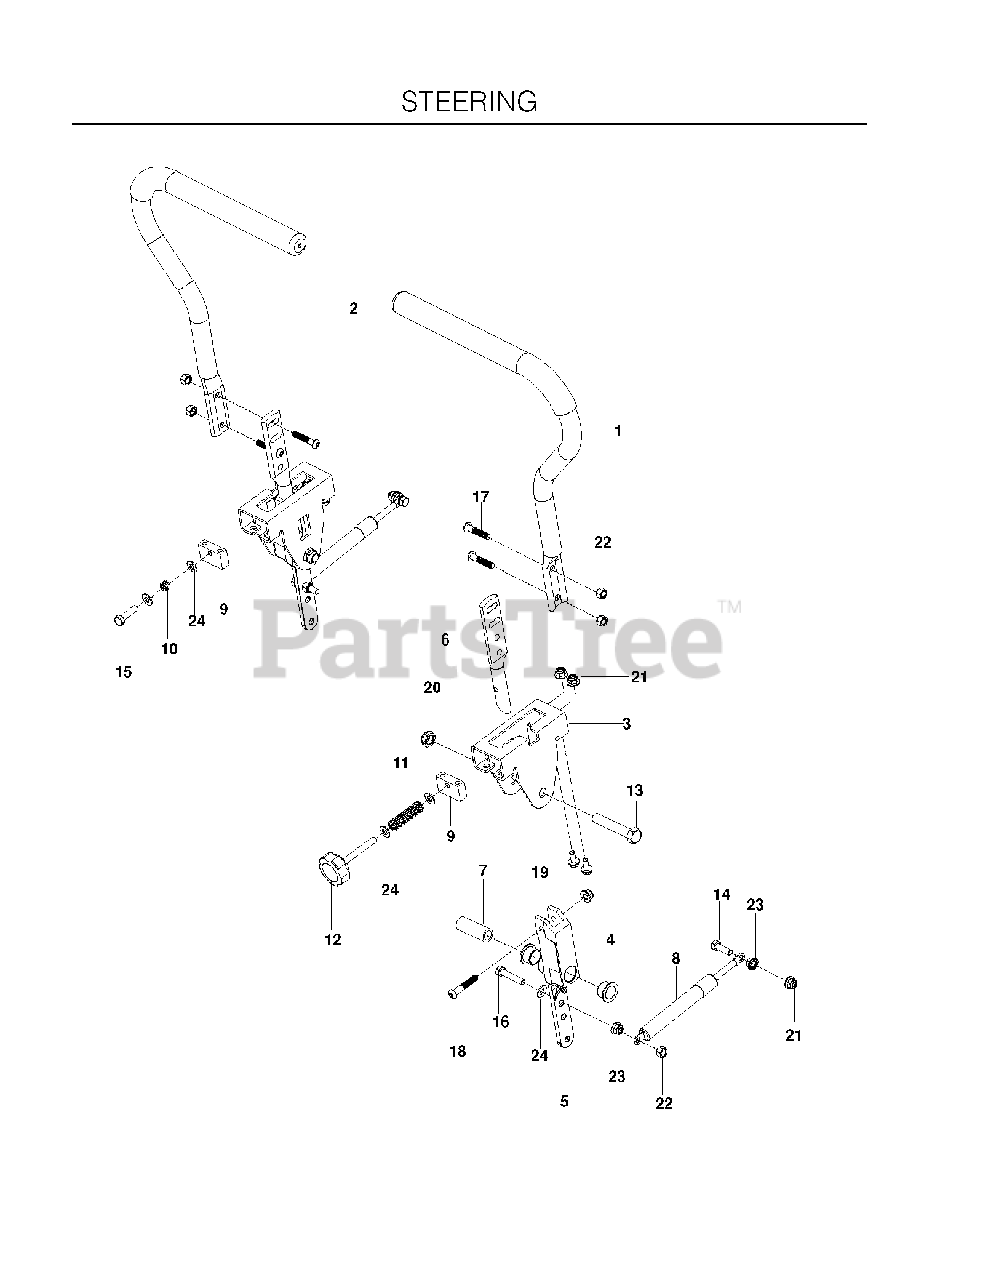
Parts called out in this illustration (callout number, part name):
1	LEVER.STEERING.ASM.(W/GRIP)
2	GRIP, DRIVE LEVER
3	BRACKET, CONTROL
4	BEARING, FLANGE
5	LEVER CONTROL PIVOT
6	LEVER.HANDLE MOUNT
7	SPACER, PIVOT CONTROL
9	BLOCK.TRACKING
11	SPRING COMPRESSION 2.0
13	HCS 1/2C X 2 3/4
14	HCS 5/16C X 1
15	CAPSCREW 5/16 X 1/1/2 HEX HEAD
16	BOLT 1/4C X 1 3/4
17	SCREW BUTTONHEAD 5/16-18X1-1/2
18	SCREW 5/16-18 X 1 3/4 BTN-HD
19	HHFS 5/16-18 X 3/4
20	NUT 1/2-13 HEX JM NYL
21	5/16-18 NYLOC FLANGE NUT
22	NUT 5/16 NYLOC
23	NUT 5/16C WHIZ
24	FLAT WASHER 5/16 SAE
